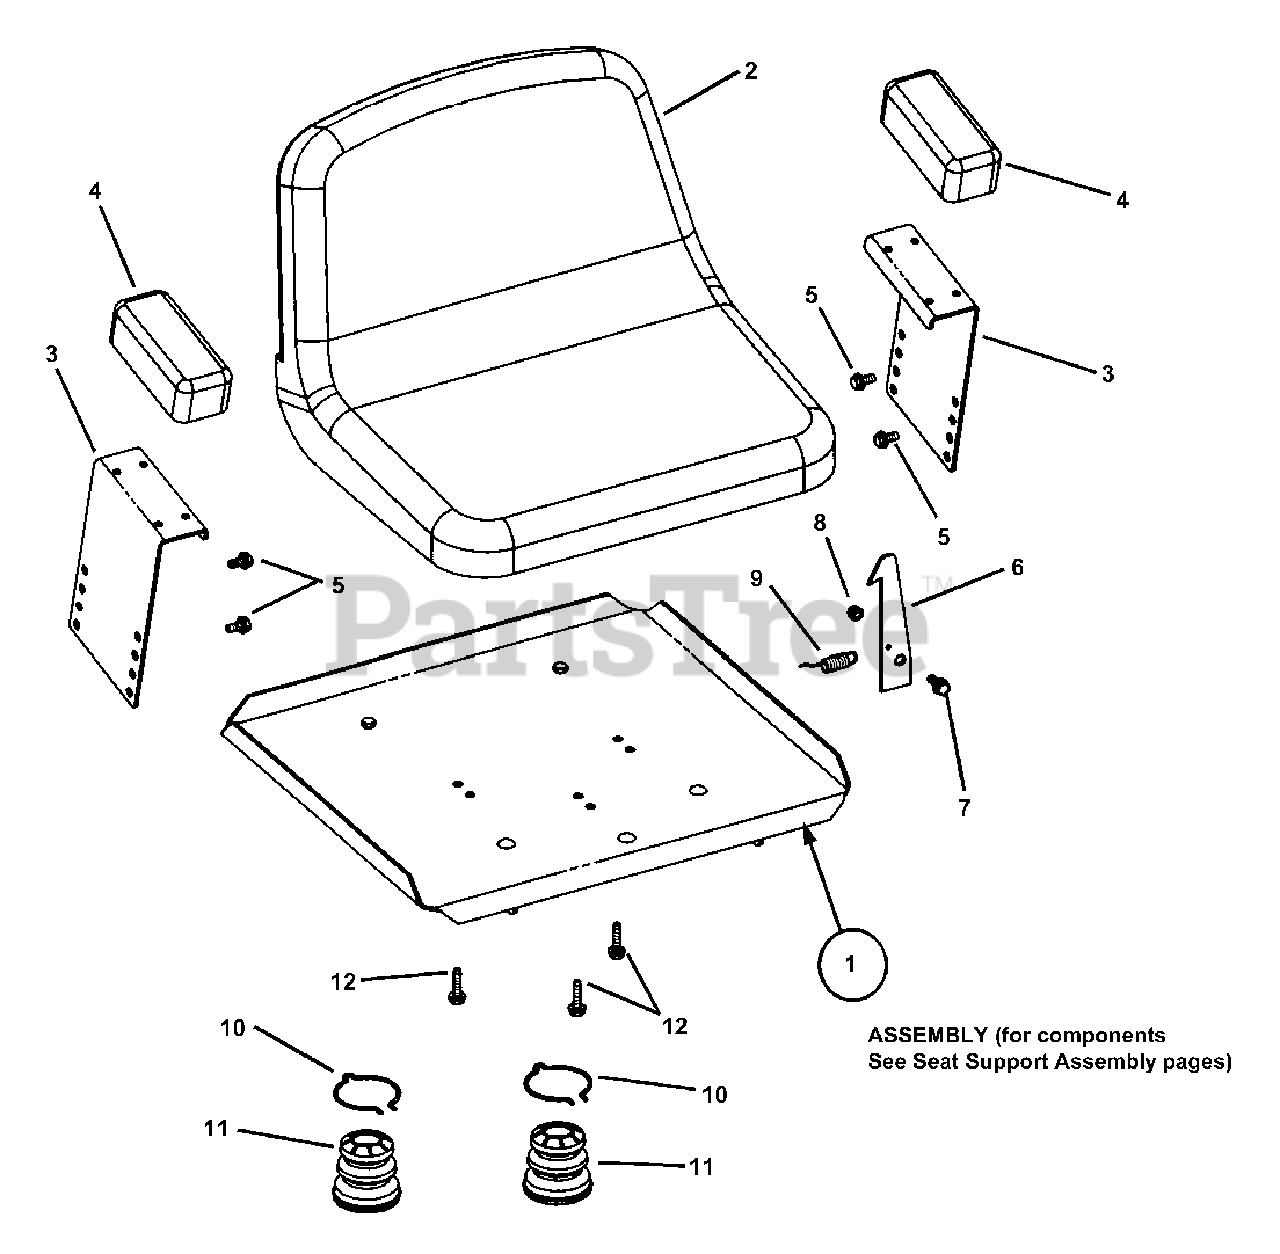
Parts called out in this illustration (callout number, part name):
1	ASSEMBLY, Seat Support
2	SEAT, Milco High Back
3	BRACKET, Armrest (Painted)
5	SCREW, 5/16-18 x 5/8" Hex Washer Self-Tap
6	LATCH, Seat Support
7	BOLT, 5/16-18 Shoulder w/ Nylon Patch
8	NUT, 5/16-18 HEX NYLON LOCK
9	SPRING, Extension
10	CLIP, Seat Cushion
11	COVER, Spring (Rubber)
12	SCREW, 5/16-18 x 1-1/4" Hex Washer Self-Tap
